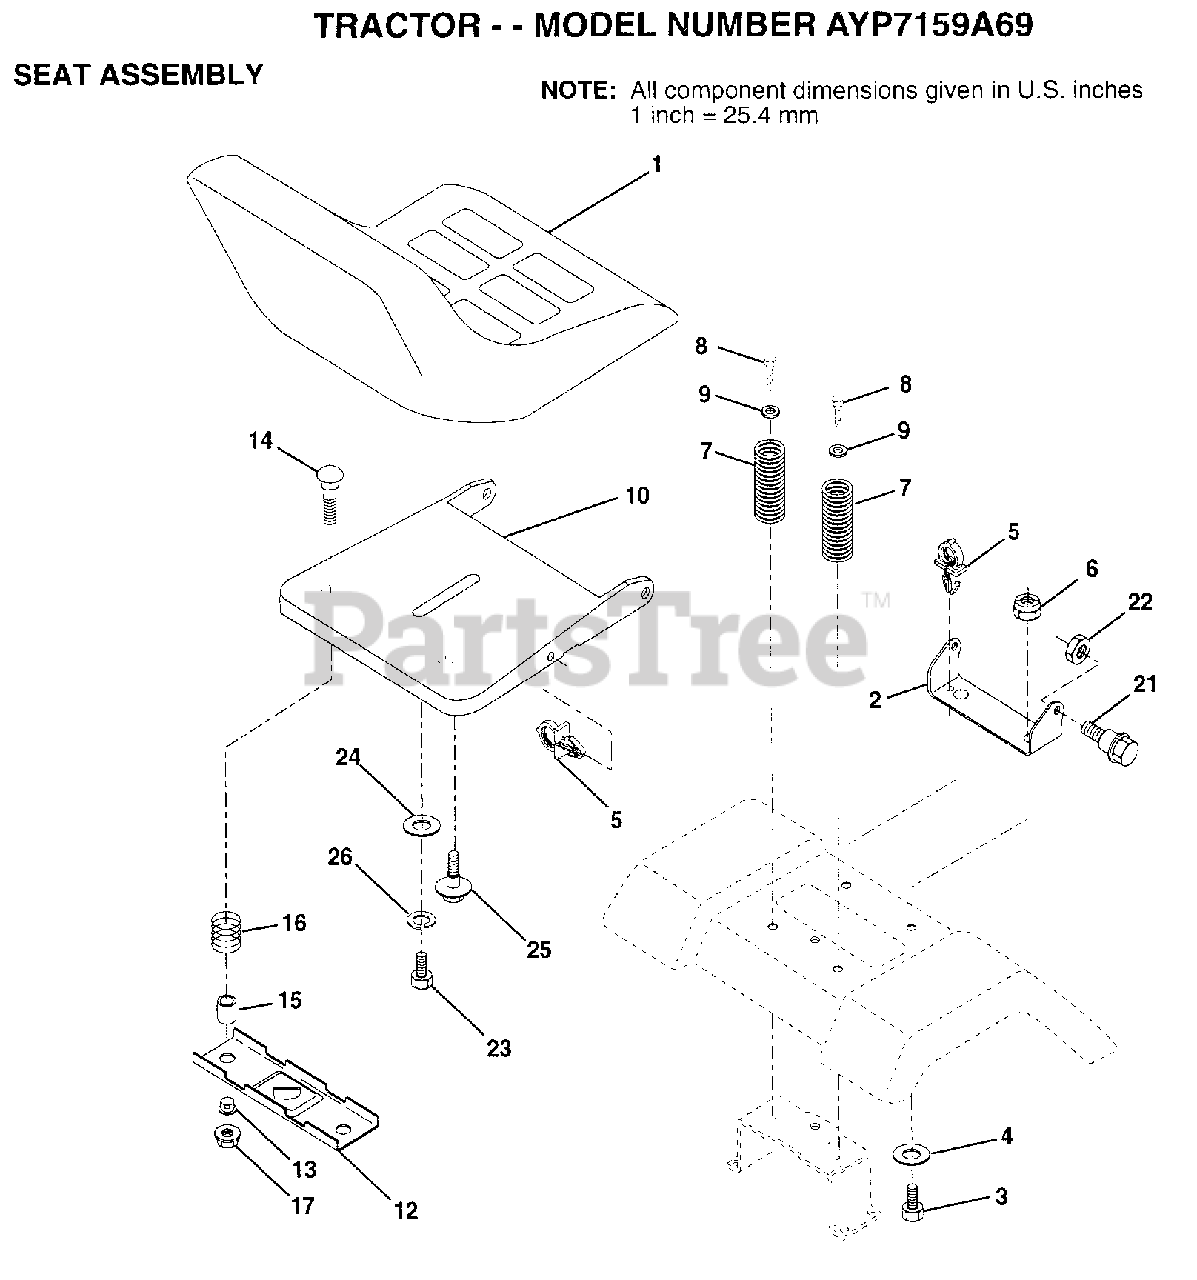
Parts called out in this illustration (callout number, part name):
1	SEAT
2	BRACKET PVT SEAT
3	BOLT
4	WASHER PM
5	CLIP.PUSH-IN.HING
6	NUT
7	SPRING COMPRESSIO
8	SCREW GTV
9	WASHER
12	BRKT SWITCH
13	BUSHING
15	SPLIT SPACER
16	SPRING
21	BOLT.SHLD.5/16-18
22	NUT
23	BOLT
24	WASHER
25	"BOLT,SHOULDER"
26	LOCKWASHER
